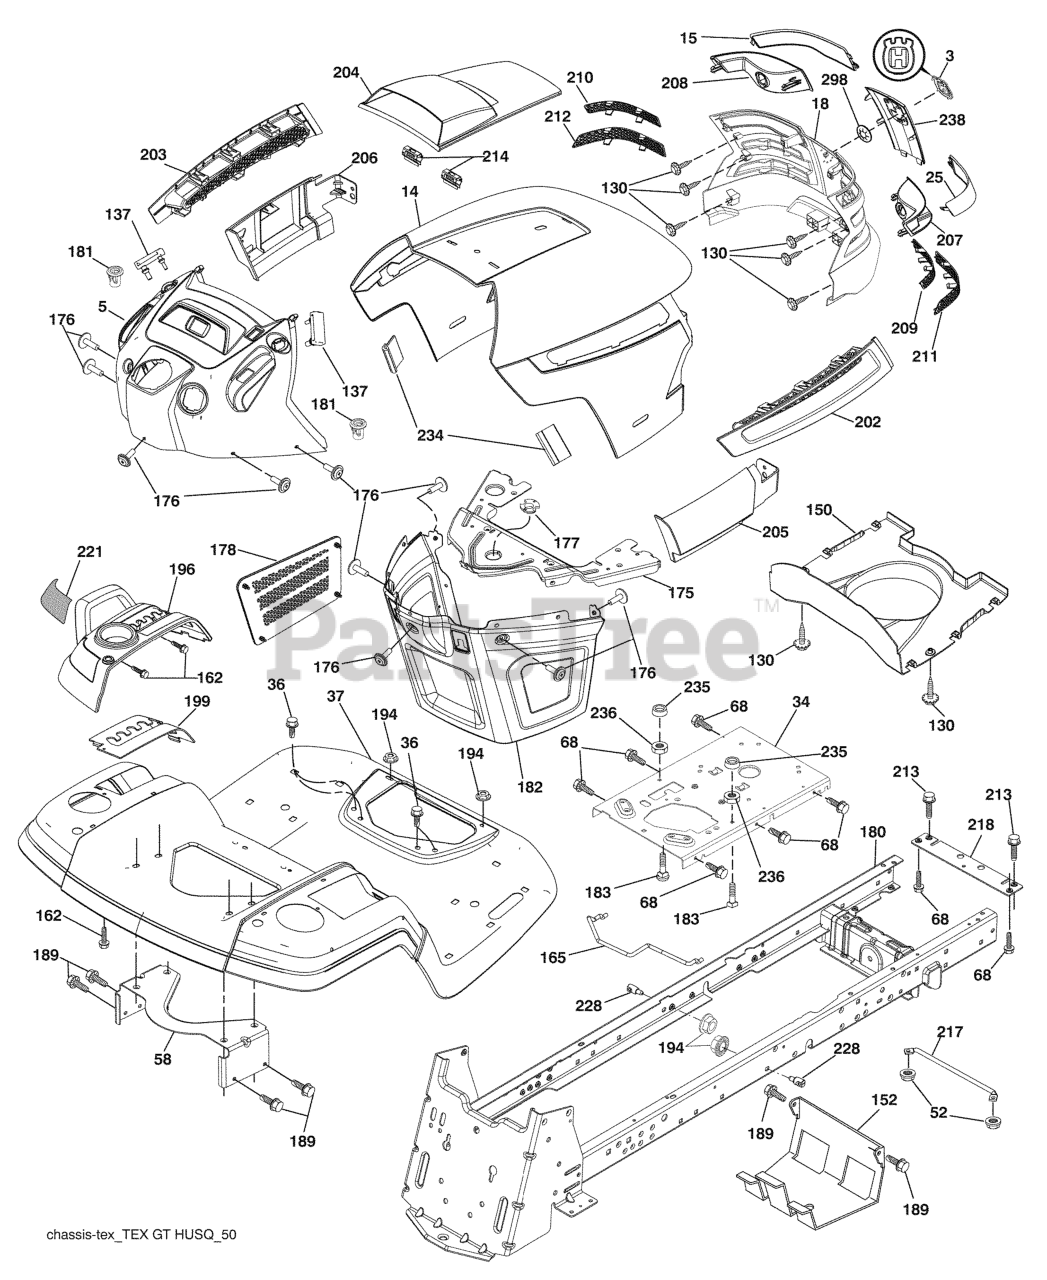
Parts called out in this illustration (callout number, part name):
3	RP LOGO
5	DASH.ASM.GTHUSQTX.RGS.ELECT.CK
14	HOOD
15	LENS.LH.TEX.GT.HUSQ.CL
18	GRILL.ASM.HUSQ.TG/CRD.W/TRIM
25	LENS.RH.TEX.GT.HUSQ.CL
34	PLATE.ENGINE.WELDED.CHASSIS
36	SCREW 5/16"
37	FENDER.PNT.TX.GT.CH/FW.ORANGE
52	LOCKNUT
58	BRKT.SUPPORT.FNDR/TANK
68	Screw 5/16-18 x 1/2
130	SCREW.#10 X 0.750.BOS
137	BUMPER DASH
150	AIR.DUCT.HOOD.TEX.GT.HUSQ
152	SHIELD.BROWNING.W/TEX
161	CONSOLE.FUEL.WINDOW.HU
162	SCREW.HI-LO.CONSOLE
165	SUPPORT.TANK.REAR.W/TEX
175	PLATE.CROSSMEMBER.HUSQ
176	SCREW.#10-24X5/8.RN.QU
177	BUSHING, STEERING
178	CARGO.ASM.NET.TXGT.W/C
180	CHASSIS.GT.SLOPED.DRAWBAR.
181	BUSHING.MNT.FEND.CRGO.
182	DASH.LOWER.COMMON.12V.ADAPTOR
183	BOLT.5/16-18X1-1/4 FULL.THREAD
189	SCREW
194	NUT LOCK HEX FLANGE 5/16-18
196	CONSOLE.ASM.DCKLFT.W/RF.HQ.DLR
199	PLATE.DECK.LIFT.HUSQVARNA.GT
202	VENT.SIDE.HOOD.HUSQ.RH.GREY
203	VENT.SIDE.HOOD.HUSQ.LH.GRAY
204	HOOD VENT
205	SKIRT.HOOD.SIDE.HUSQ.RH.GREY
206	SKIRT.HOOD.SIDE.HUSQ.LH.GREY
207	BEZEL.RH.TEX.GT.HUSQ
208	BEZEL.LH.TEX.GT.HUSQ
209	INSERT.HEX.GRILL.HUSQ.GREY
210	INSERT.HEX.GRILL.HUSQ.
211	INSERT.HEX.GRILL.HUSQ.
212	INSERT.HEX.GRILL.HUSQ.
213	BOLT
214	CLIP.RETAINER.TINNER.
217	ROD.PIVOT.HOOD
218	X-PIECE.HOOD.STOP.NON/
221	REFLECTOR.LH.TEX GT HU
228	STUD.FASTNER.W/ANTI-ROTATE
234	BUMPER.HOOD.TEX.HUSQVARNA
235	SPACER FENDER
236	NUT.CENTERLOCK.5/16-
238	TRIM.HUSQ.TG/CRD.SERVICE
298	NUT PUSH M
